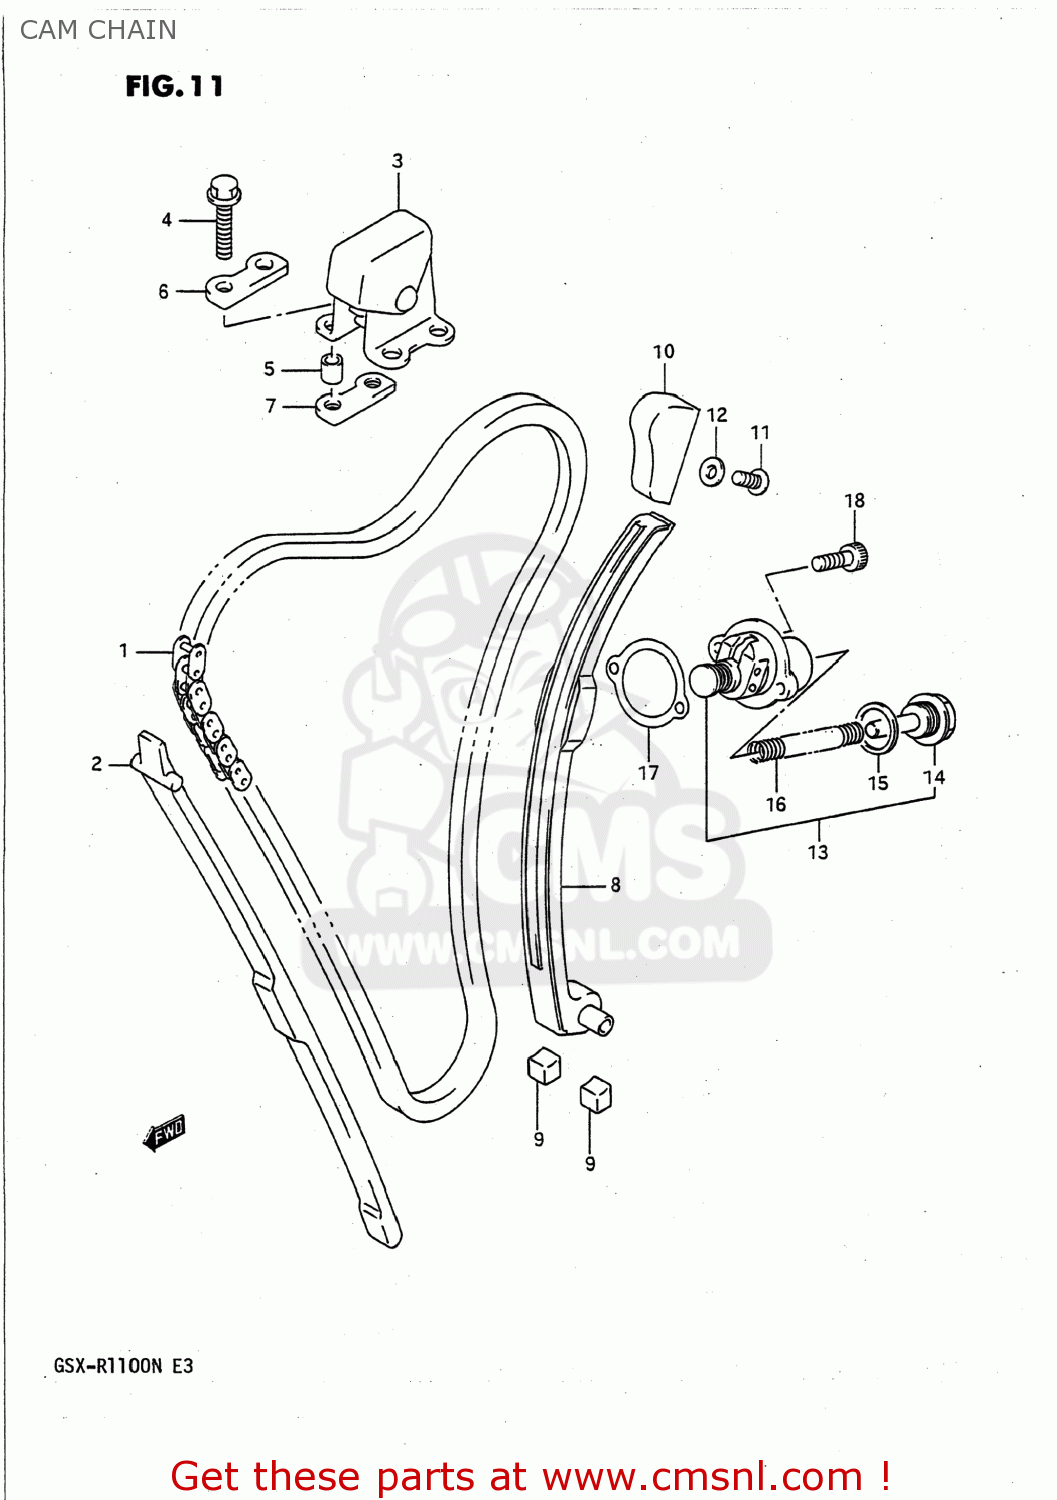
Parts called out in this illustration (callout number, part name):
1	CHAIN,CAMSHAFT DRIVE
2	GUIDE,CAM CHAIN NO.1
3	IDLER,CAM CHAIN
4	BOLT
5	SPACER (6,8X10X9.4)
6	CUSION,IDLER
7	CUSHION,IDLER
8	TENSIONER,CAM CHAIN
9	CUSHION,CAM CHAIN TENSIONER
10	GUIDE,CAM CHAIN NO.2
11	BOLT
12	GASKET(5.8X13X1.2) (NAS)
13	ADJUSTER ASSEMBLY,TENSIONER
14	PLUG
15	GASKET (NAS)
16	SPRING
17	GASKET,TENSIONER ADJUSTER (NAS)
18	BOLT
